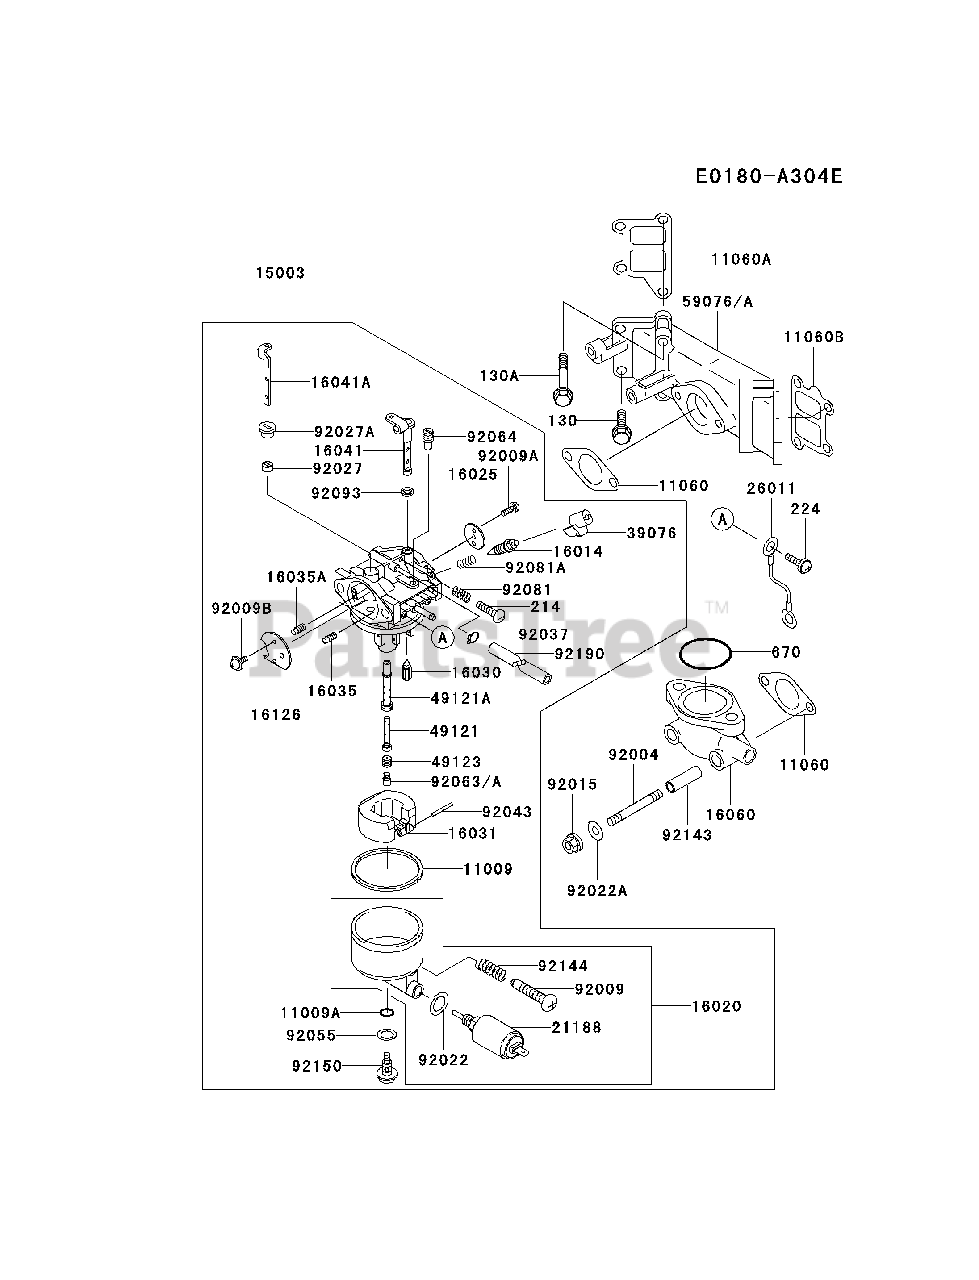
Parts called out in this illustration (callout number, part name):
130	BOLT-FLANGED
130A	BOLT-FLANGED
214	SCREW-PAN+-
224	SCREW-PAN-WP-CROS
670	O RING
